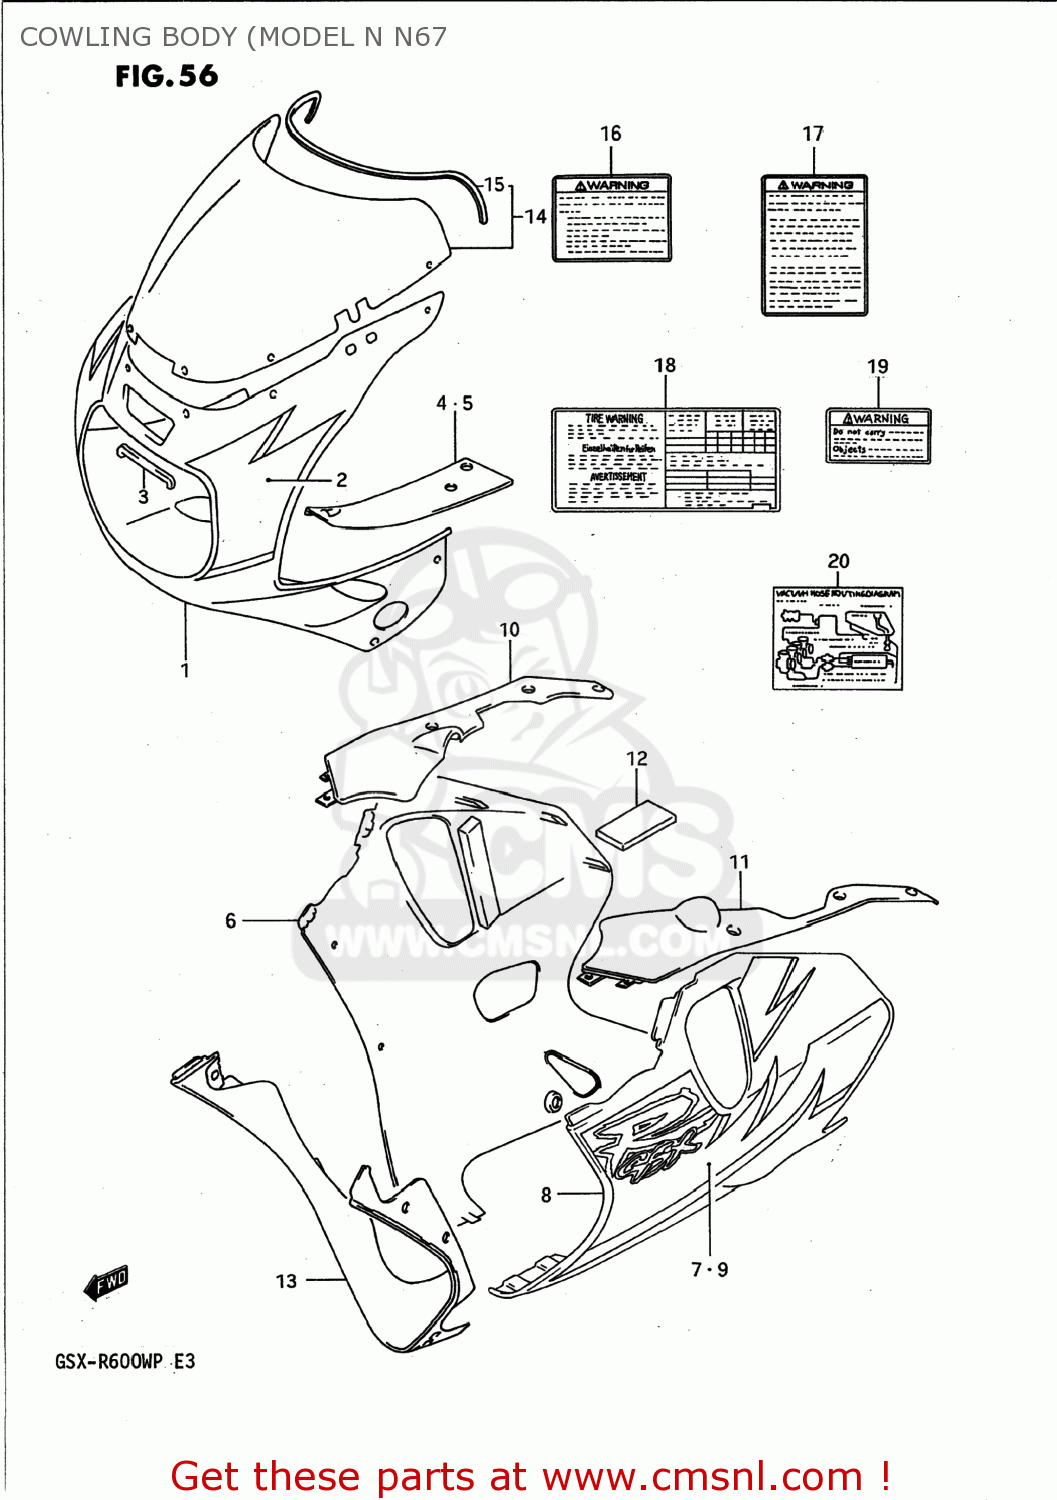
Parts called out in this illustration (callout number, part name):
1	COWLING ASSY,BODY
2	TAPE SET,COWLING,UPPER
3	CUSHION,FR POSITION LAMP
4	PANEL,UPR,R
5	PANEL,UPR,L
6	COWLING ASSEMBLY,UNDER,RIGHT
7	STRIPING.KUIP R
8	COWLING ASSY,UNDER,L
9	TAPE SET,COWLING,UNDER
10	PANEL,LWR,R
11	PANEL,LWR,L
12	CUSHION,PANEL
13	COWLING,UNDER CTR
14	WINDSCREEN SET
15	MOLDING
16	LABEL
17	LABEL (WARNING SCREEN)
18	LABEL (TIRE AIR PRESSURE)
19	LABEL,WARNING STEERING
20	LABEL (VACUUM HOSE ROUTING)
